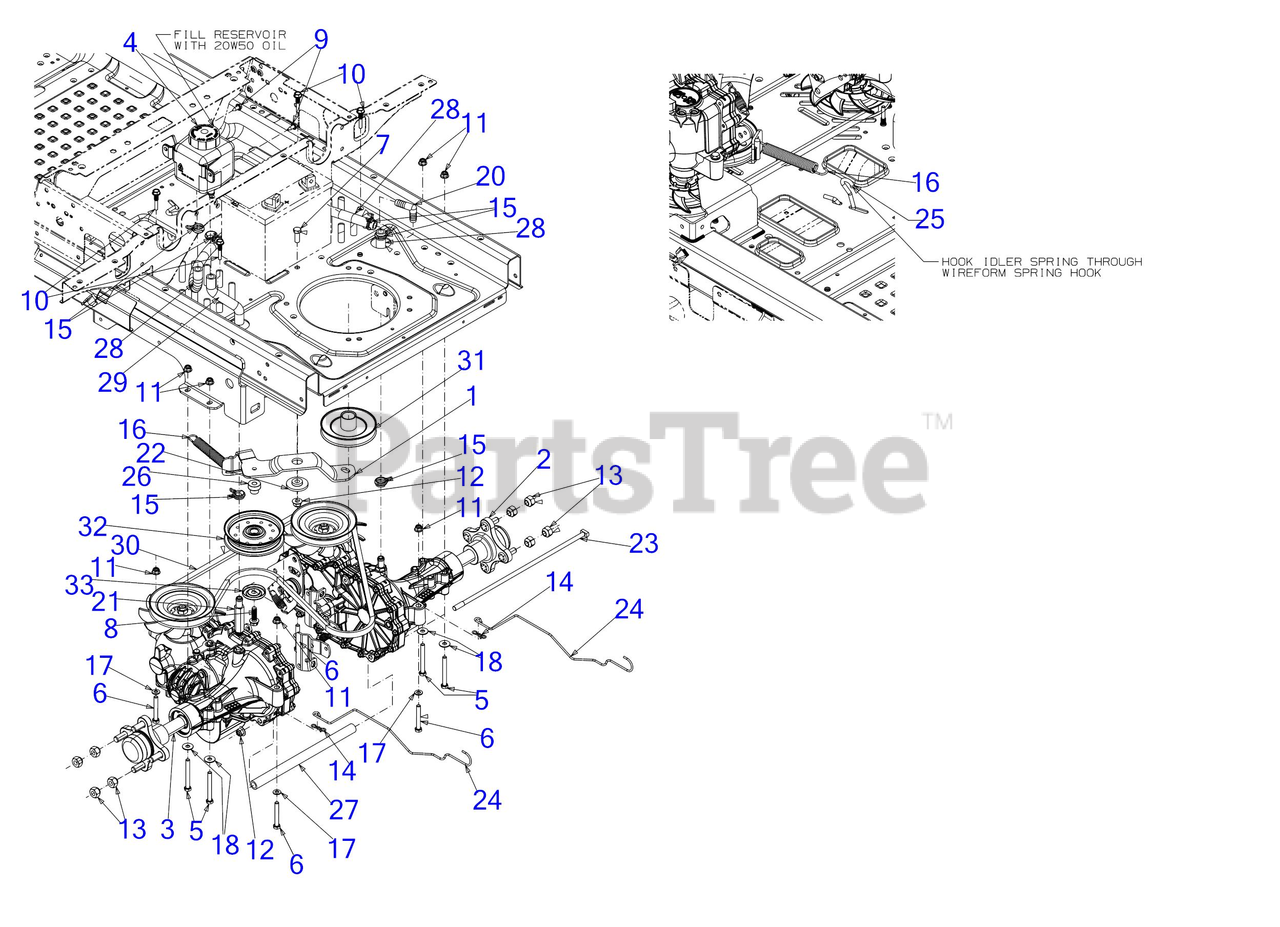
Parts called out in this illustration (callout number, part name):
1	IDLER BRACKET ASSEMBLY
2	HYDRO TRANSMISSION ASSEMBLY (RH)
3	HYDRO TRANSMISSION ASSEMBLY (LH)
4	HYDRAULIC TANK
5	HEX SCREW 5/16-18 x 2.75
6	HEX SCREW 5/16-18 x 2.25 GR5
7	SCREW 3/8-16 x 1 GR5
8	SCREW 3/8-16 X1.250
9	SCREW 1/4-20X.625
10	BELT KEEPER ROD .25 x 1.585
11	FLANGE LOCK NUT 5/16-18
13	LUG NUT 7/16-14
14	BOW TIE COTTER PIN 1/4-5/16
15	FUEL HOSE CLAMP
16	EXTENSION SPRING .75 DIA x 5.87
17	FLAT WASHER
18	FLAT WASHER
20	90 DEGREE NYLON FITTING
21	EXTENSION FITTING 9/16-18
22	SHOULDER SPACER
23	SUPPORT TUBE ROD
24	HYDRO BYPASS ROD
25	IDLER SPRING HOOK
26	SHOULDER SPACER
27	TRANSMISSION SPACER .75OD x 11.31
28	FUEL LINE 1/2" ID
29	TRANSMISSION EXPANSION HOSE
30	TRANSMISSION DRIVE BELT A x 67
30	Cub Cadet TRANS DRIVE BELT A x 67 RZT
30	Troy-Bilt TRANSMISSION DRIVE BELT
31	TRANSMISSION DRIVE PULLEY
32	IDLER PULLEY 4.25 DIA
33	IDLER PULLEY CAP
